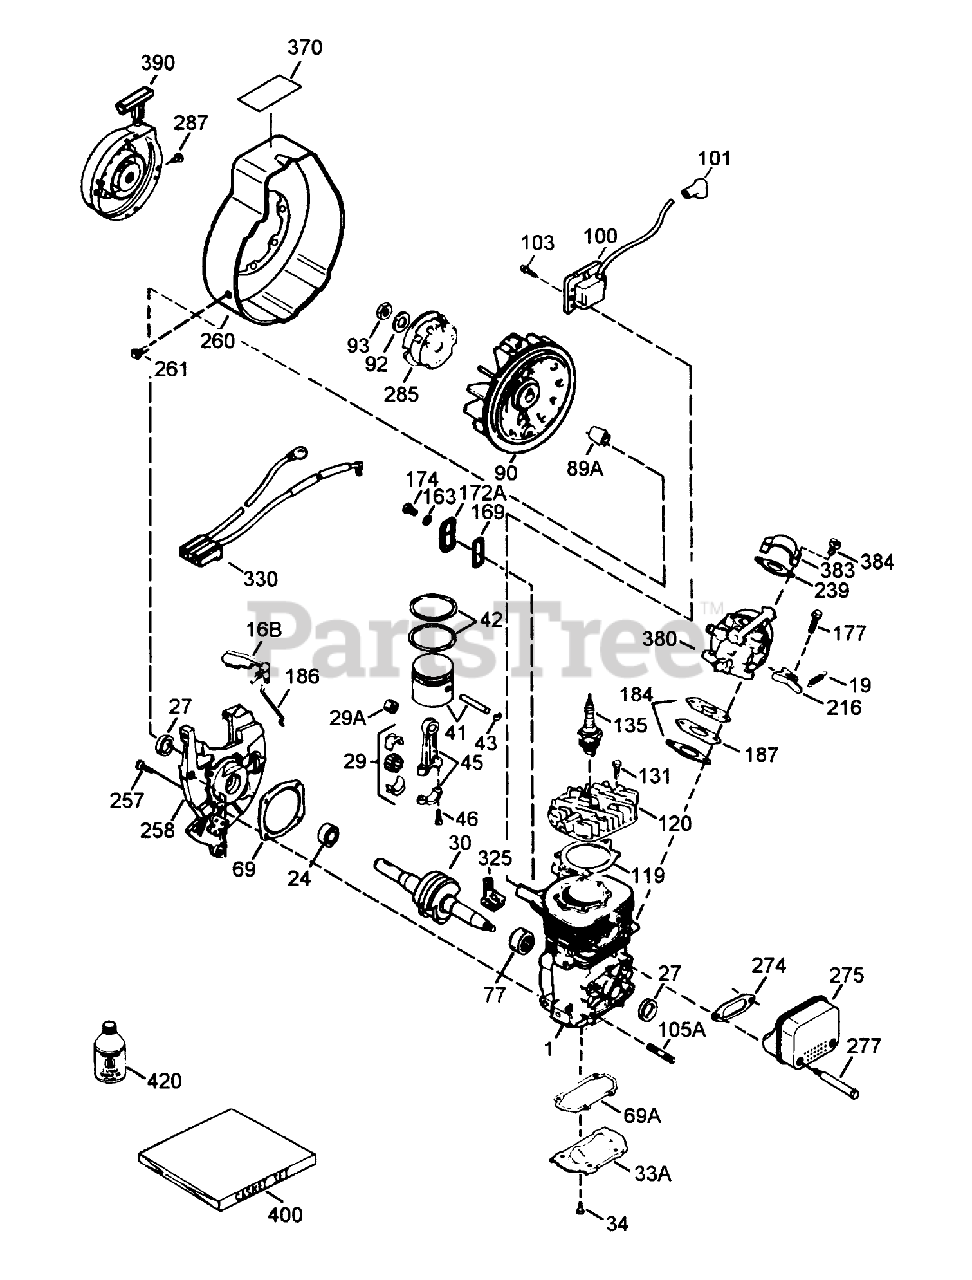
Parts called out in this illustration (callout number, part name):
1	Cylinder (Order Short Block if Replacement is Needed)
16B	Vane-Air
19	Spring-Extention
24	Bearing-Ball
27	Seal-Oil
29	Needle Bearing and Liner Set (37 Needles)
29A	Bearing-Cartridge
30	Crankshaft
33A	Plate-Cover
34	Screw (T-25, 10-24 x 1/2)
41	Piston (Incl. Ref. #43)
42	Ring Set
43	Ring-Retaning
45	Rod Assy.-Connecting (Incl. Ref. #3, 3A 3B)
46	Bolt-Rod, Connecting
69	Gasket-Cover, Cylinder
69A	Gasket-Plate, Cover
77	Bearing-Cartridge
89A	Blade (20 inch)
90	Flywheel
92	Washer-Belleville
93	Nut-Flywheel
100	Solid State
101	Cover-Spark Plug
103	Screw
119	Gasket-Head, Cylinder
120	Head-Cylinder
131	Screw (T-30, 1/4-20 x 3/4)
135	Spark Plug-Resistor (R C J 8Y)
163	Washer
169	Cover-Compression, Release
172A	Cover-Release, Compression
174	Screw (T-25, 10-24 x 1/2)
177	Screw (5/32 Allen, 1/4-20 x 1)
184	Gasket-Carburetor
186	Governor-Link
187	Spacer
216	Lever-Adjusting, Rpm
239	2060A77 WIZARD ROTA
257	Screw (T-30, 1/4-20 x 5/8)
258	Base Assy.-Blower Housing (Incl. Ref. #10)
260	Blower Housing
261	Screw (1/4-20 x 1/2)
274	Exhaust Gasket
275	Muffler (Incl. Ref. #274 277)
277	Screw (1/4-20 x 2-3/4)
285	Cup-Starter
287	Screw (8-32 x 21/64)
325	Clip-Wire
330	Harness-Wire
370	Decal-Warning
380	Carburetor (Incl. Ref. #184A)
383	Baffle-Carburetor
384	Screw
390	Rewind Starter
400	Gasket Set
420	2-Cycle Oil (8oz)
